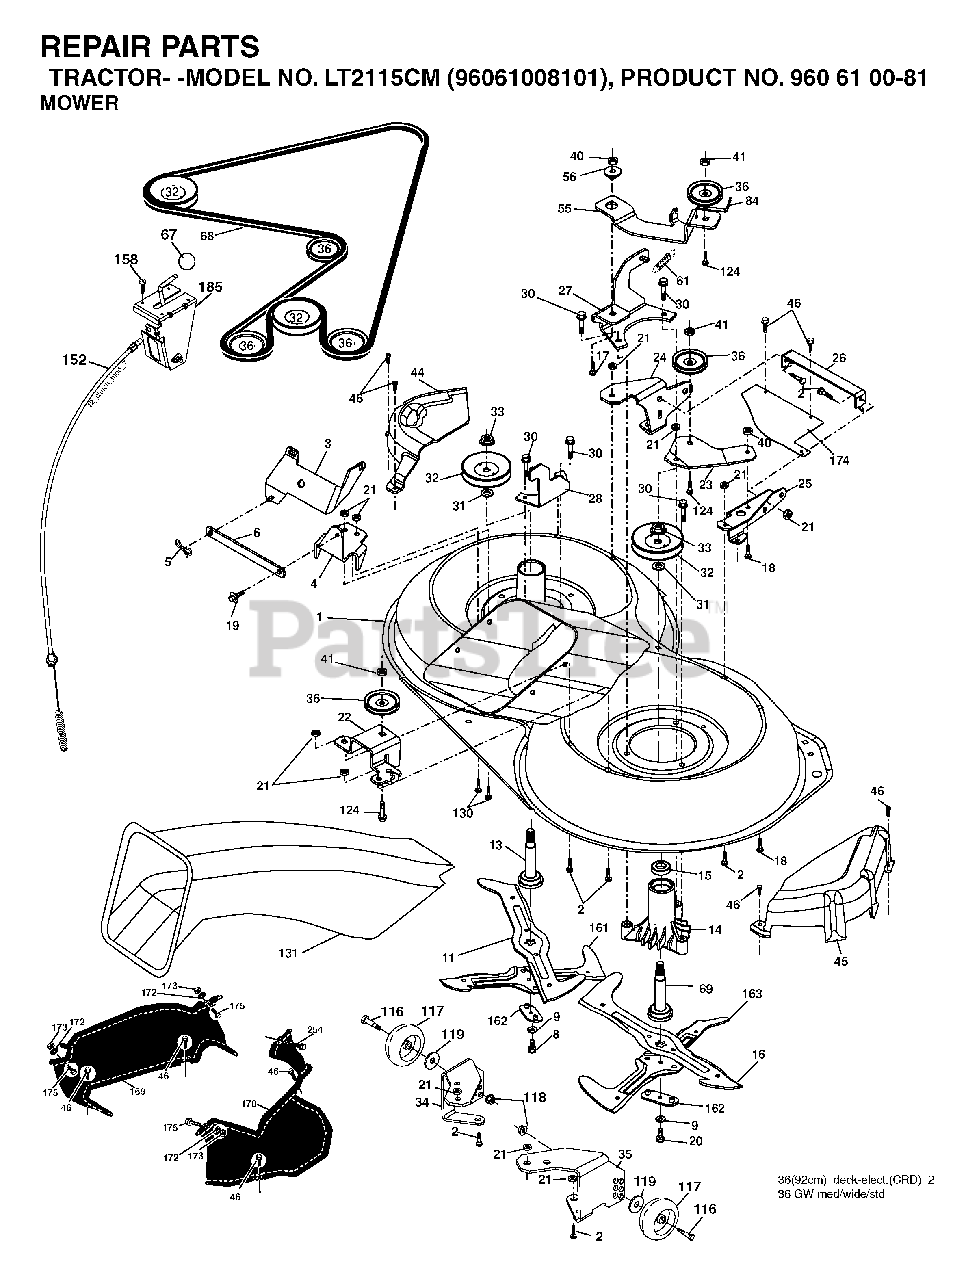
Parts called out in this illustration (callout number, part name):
2	BOLT
3	BRACKET
5	RETAINER-SPRNG RB
6	BAR SWAY
9	LOCKWASHER
13	SHAFT ASM VENT
14	HSG MANDREL
17	BOLT.3/8-14X1.25
19	BOLT SHD 5/16-18
21	LOCKNUT
24	BRACKET
25	BRACKET
28	BRACKET
30	SCREW, WASHER HEAD
31	WASHER.SPACER.MANDREL
32	PULLEY, MANDREL
33	NUT.FLANGE.LOCK.TOP
36	PULLEY.IDLER.4.25
40	LOCKNUT
41	NUT LOCK FLG 3/8-16 UNC
45	MANDREL COVER
46	SCREW.1/4-20X5/8
56	SPACER.RETAINER.MOWER
61	SPRING.TENSION.BELT
67	KNOB T (3/8 HOLE)
69	SHAFT.ASM.W/LWR.BRG.RH.THREAD
84	KEEPER, BELT IDLER
116	SHOULDER BOLT
117	WHEEL. GUAGE RALLY
118	LOCKNUT
119	WASHER
124	BOLT.3/8-16X1.50
131	CHUTE BAGGER
158	SCREW
169	COVER TERMINAL BATTERY
172	PUSH.NUT.ROUND.3/8.DIAM
173	NUT
185	HEAD ASM. CABLE CLUTCH
254	SCREW 3/8-16X1
